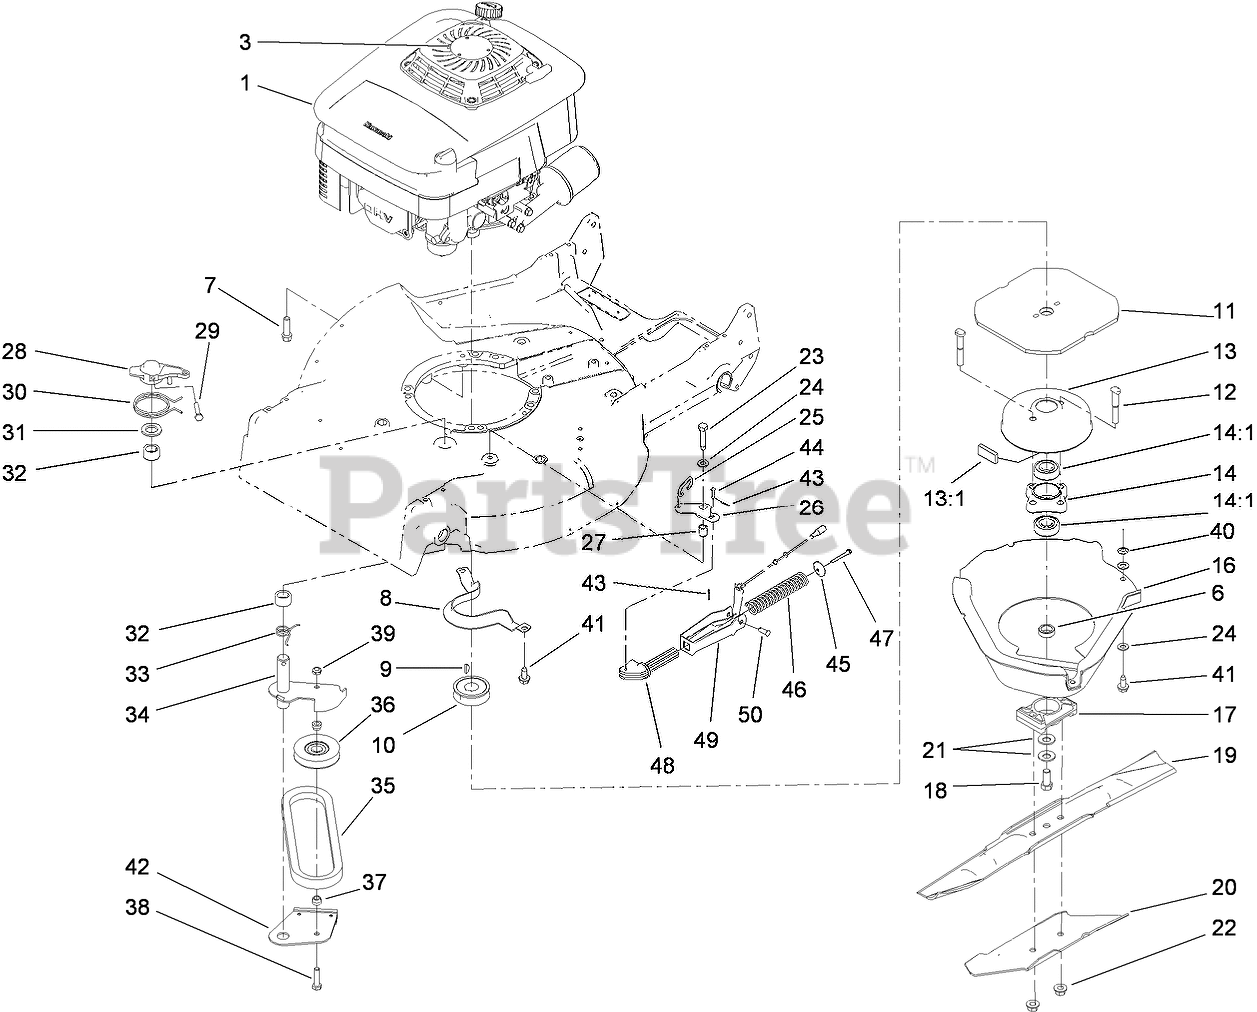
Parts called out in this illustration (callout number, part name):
1	ENGINE ASM
6	SPACER-SHAFT, OUTPUT
7	SCREW-TAPTITE
8	BRACKET-GUIDE, BELT
9	KEY-WOODRUFF
10	PULLEY-DRIVER
11	FLYWHEEL-BBC
12	BOLT-BLADE
13	BRAKE DRUM ASM
13:1	DAMPENER-VIBRATION
14	HUB ASM
14:1	BEARING-BALL
16	SHIELD
17	SPACER-BLADE
18	SCREW-HH
19	BLADE-21 INCH
20	STIFFENER-BLADE
21	WASHER-SPRING
22	NUT-LOCK
23	SCREW-HH
24	WASHER-PLAIN
25	LINK-CONTROL
26	BELLCRANK
27	SLEEVE-BELLCRANK
28	LEVER
29	SCREW-HH
30	SPRING-TORSION
31	WASHER
32	BEARING
33	SPRING-TORSION
34	ARM-IDLER
35	V-BELT
36	PULLEY-IDLER
37	SPACER-PULLEY, IDLER
38	SCREW-HH
39	NUT-LOCK, NI
40	NUT-PUSH
41	SCREW-HWHTF
42	BRAKE PLATE ASM
43	PIN-COTTER
44	PIN-SPRING
45	RETAINER-SPRING
46	SPRING
47	SCREW-HWHTF
48	GUIDE-SPRING
49	BRACKET-SPRING
50	PIN-CABLE
